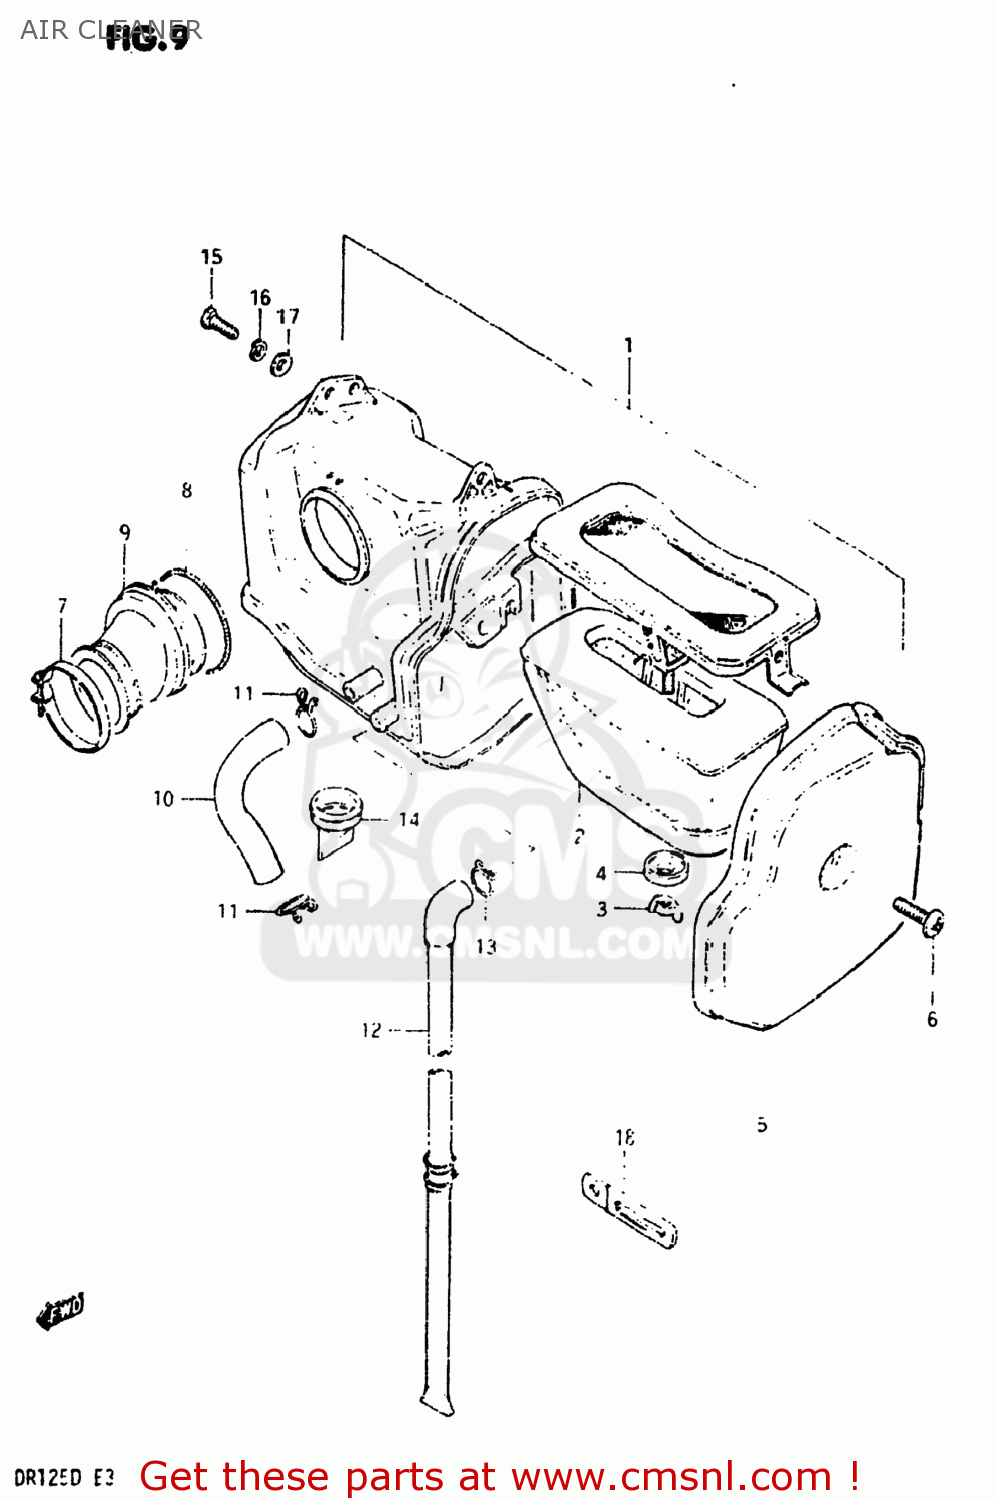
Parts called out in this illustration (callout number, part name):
1	CLEANER ASSEMBLY,AIR
2	ELEMENT,AIR CLEANER
3	NUT
4	WASHER
5	CAP
6	SCREW
7	CLAMP
8	CLAMP,CLEANER SIDE
9	TUBE,OUTLET
10	TUBE,AIR CLEANER BREATER
11	CLAMP
12	HOSE,AIR CLEANER DRAIN
13	CLAMP
14	DRAIN TUBE
15	BOLT, UPPER
16	LOCK WASHER
17	WASHER
18	CLAMP
